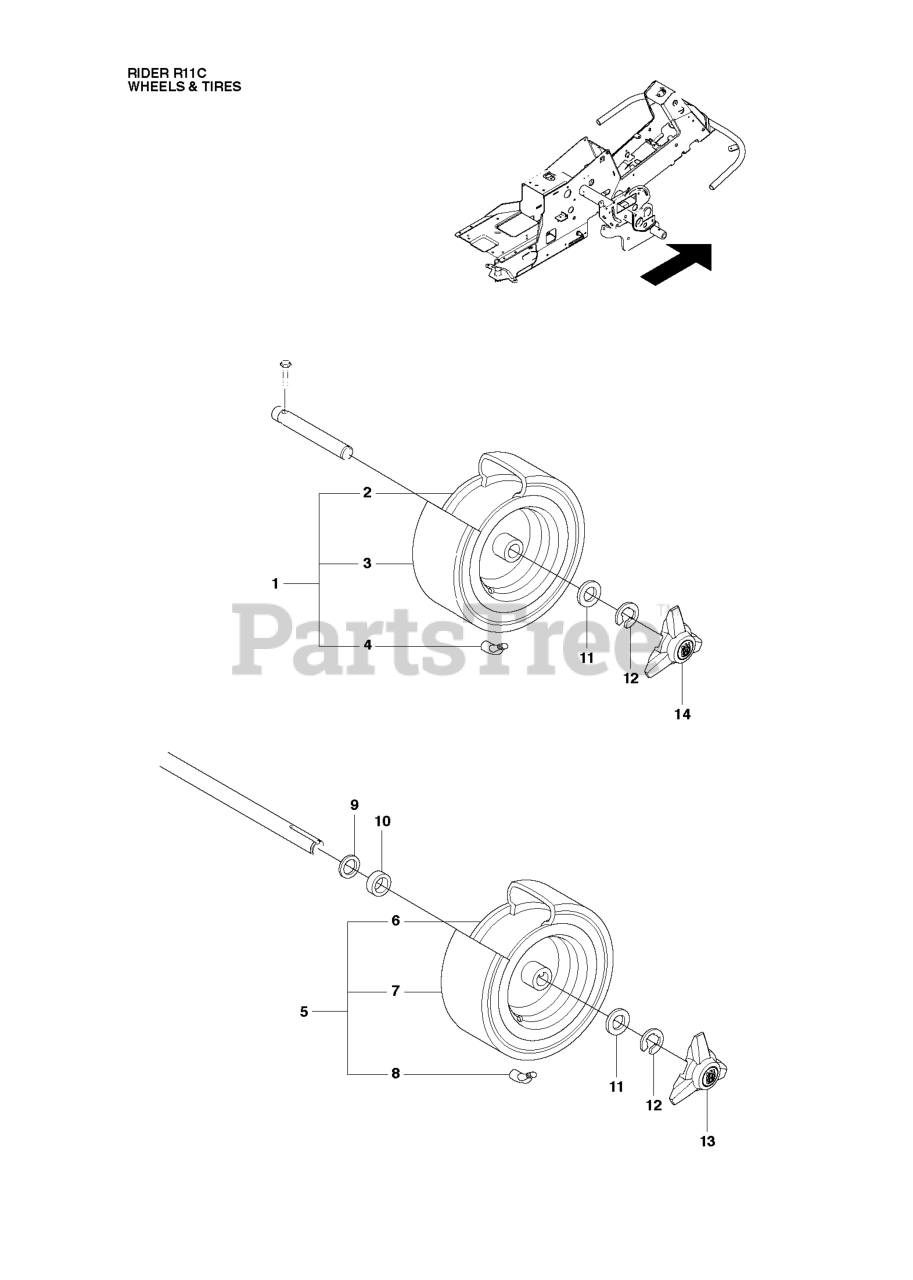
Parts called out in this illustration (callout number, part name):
5	WHEEL
6	RP RIM
12	RETAINING RING
